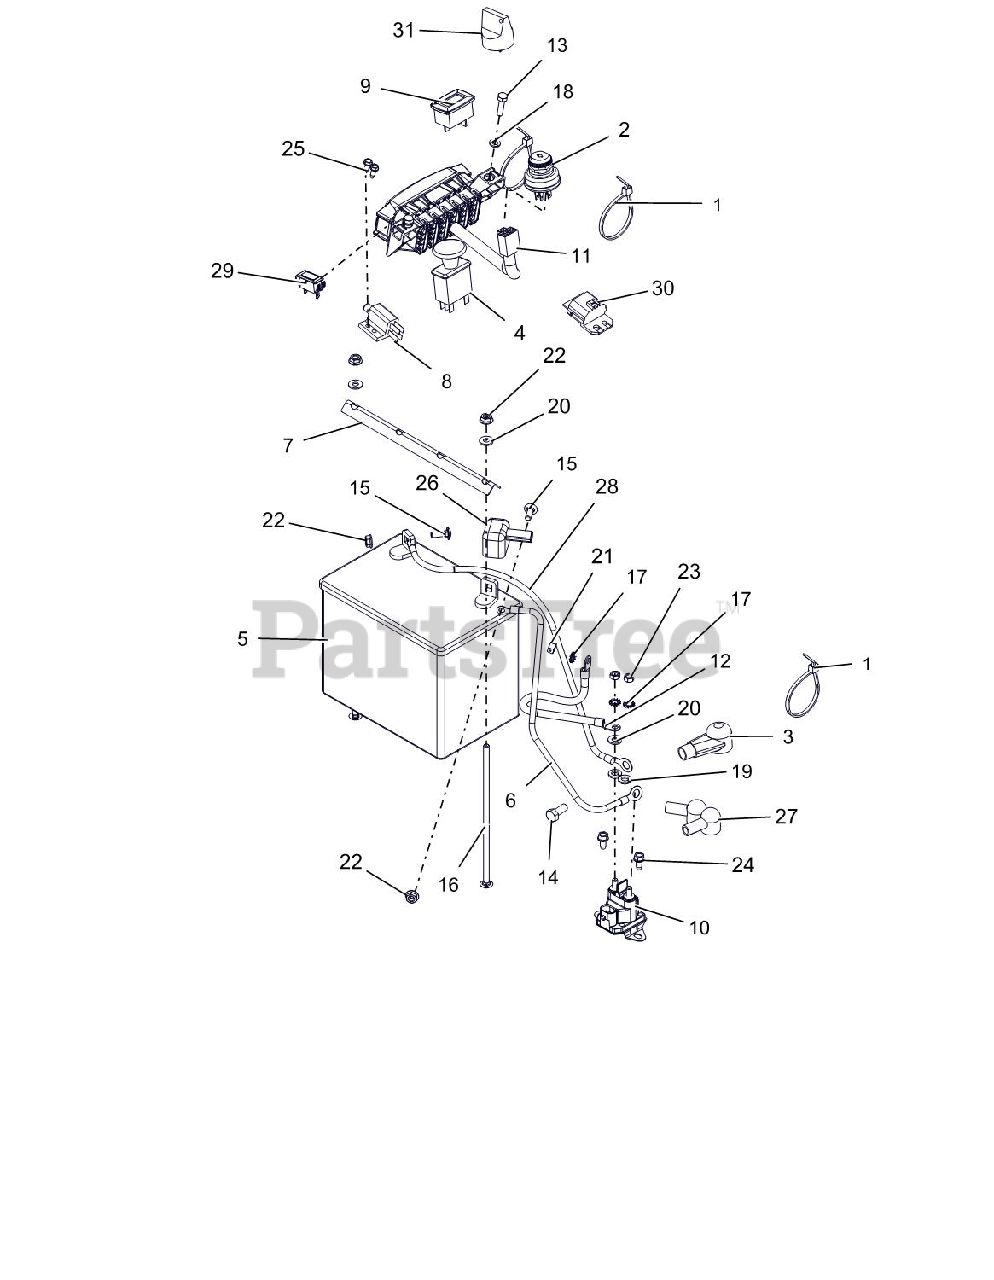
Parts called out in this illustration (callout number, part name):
1	CABLE TIE, .15 X 8.50
2	SWITCH, IGNITION
3	BOOT, BATTERY TERMINAL-RED
4	SWITCH, CLUTCH
5	BATTERY, 300 CCA 10U1L
6	CABLE, STARTER 13.00"
7	HOLD DOWN
8	SWITCH- DOUBLE POLE N.O./N.O.
9	METER, HOUR W/MAINTENANCE
10	SOLENOID, STARTER (SEALED)
11	HARNESS, PROSTANCE WIRING
11	FUSE,10 AMP MINI-ATC
11	FUSE,15 AMP MINI-ATC
11	FUSE,20 AMP MINI ATC
11	RELAY,MICRO5 TERML W/RESISTOR
11	DIODE, CONNECTOR SHELL
11	FUSE, 20 AMP BLADE S/O
12	CABLE, POS W/(2)1/4 RING 9.0LG
13	@BLT-HEX M6-1.0X25 YWZC
14	@BLT-HEX M8-1.25X20 YWZC
15	@BLT-RDHDSQNK .25-20X.75 G5YZ
16	BLT-RDHDSQNK .25-20X7.50 GR2YZ
17	@WSHR-LK-EXT.262X.502X.026YWZC
18	@WSHR-LK .25X.062 REG YWZC
19	@WSHR-LK .31X.078 REG YWZC
20	@WSHR-FL-STL.281X.62X.065 YWZC
21	@NUT-LK-CTR .25-20 YWZC
22	@NUT-SPNLK-FLG .25-20 YWZC
23	NUT-HEX M6X1.0 YWZC
24	SCR-TAP .25-20X.50 HWH TR YWZ
25	@SCR-TAP 10-24X.50 HWH TR YWZC
26	INSULATOR
27	BOOT, EYELET TERMINAL
28	CBL,NEGATIVE BATTERY 20.00
29	LIGHT,INDICATOR
30	MODULE,INTERLOCK,DELAY, 1801
31	KEY, W/ SHIELD
